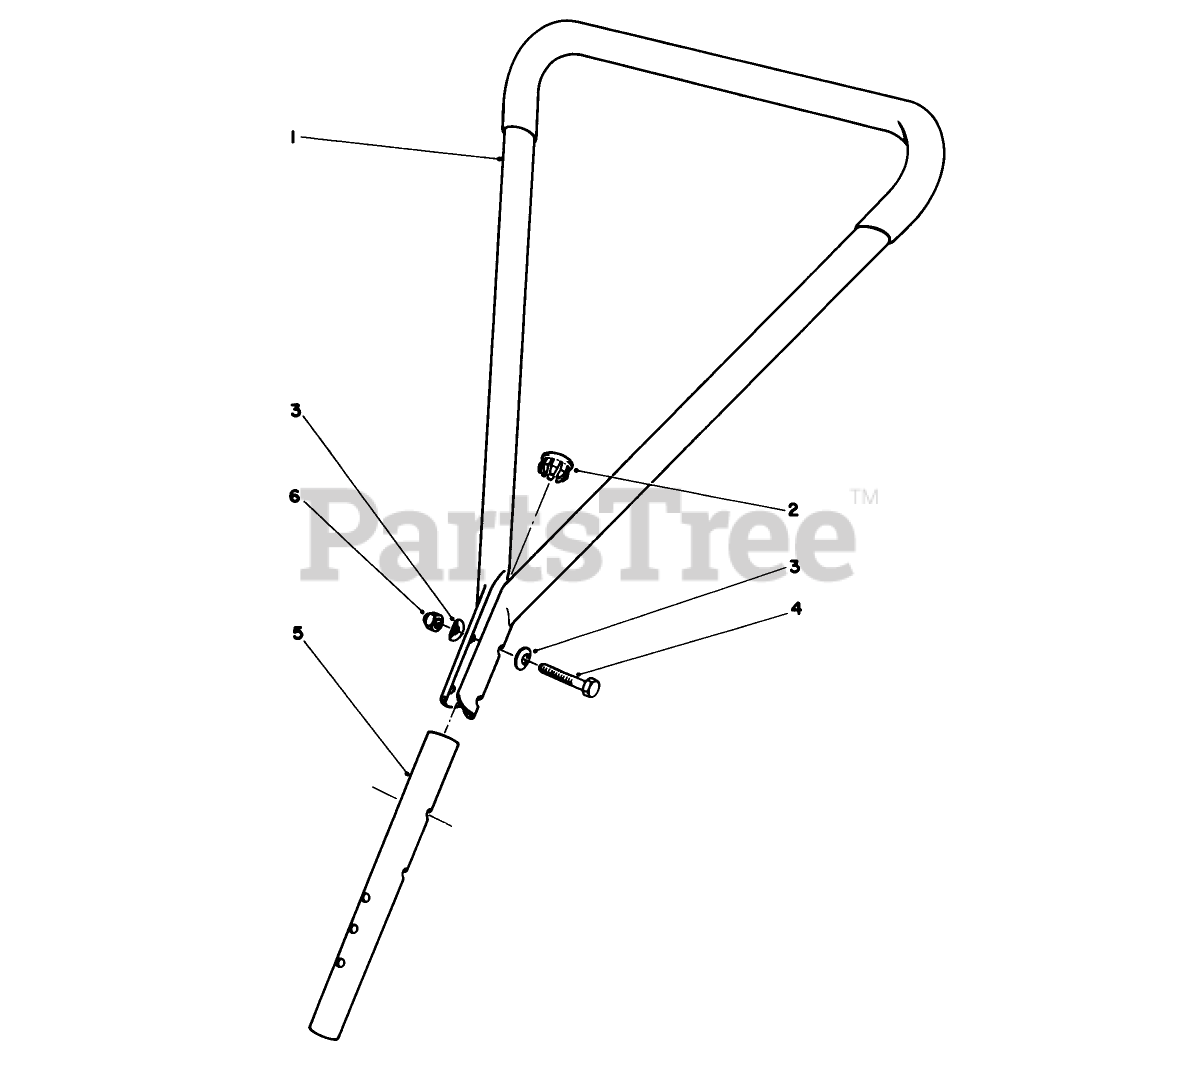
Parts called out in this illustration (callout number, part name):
1	Tube-Handle
2	Closure-Tube
3	WASHER
4	SCREW-HH
5	Tube-End
6	NUT-CAP
